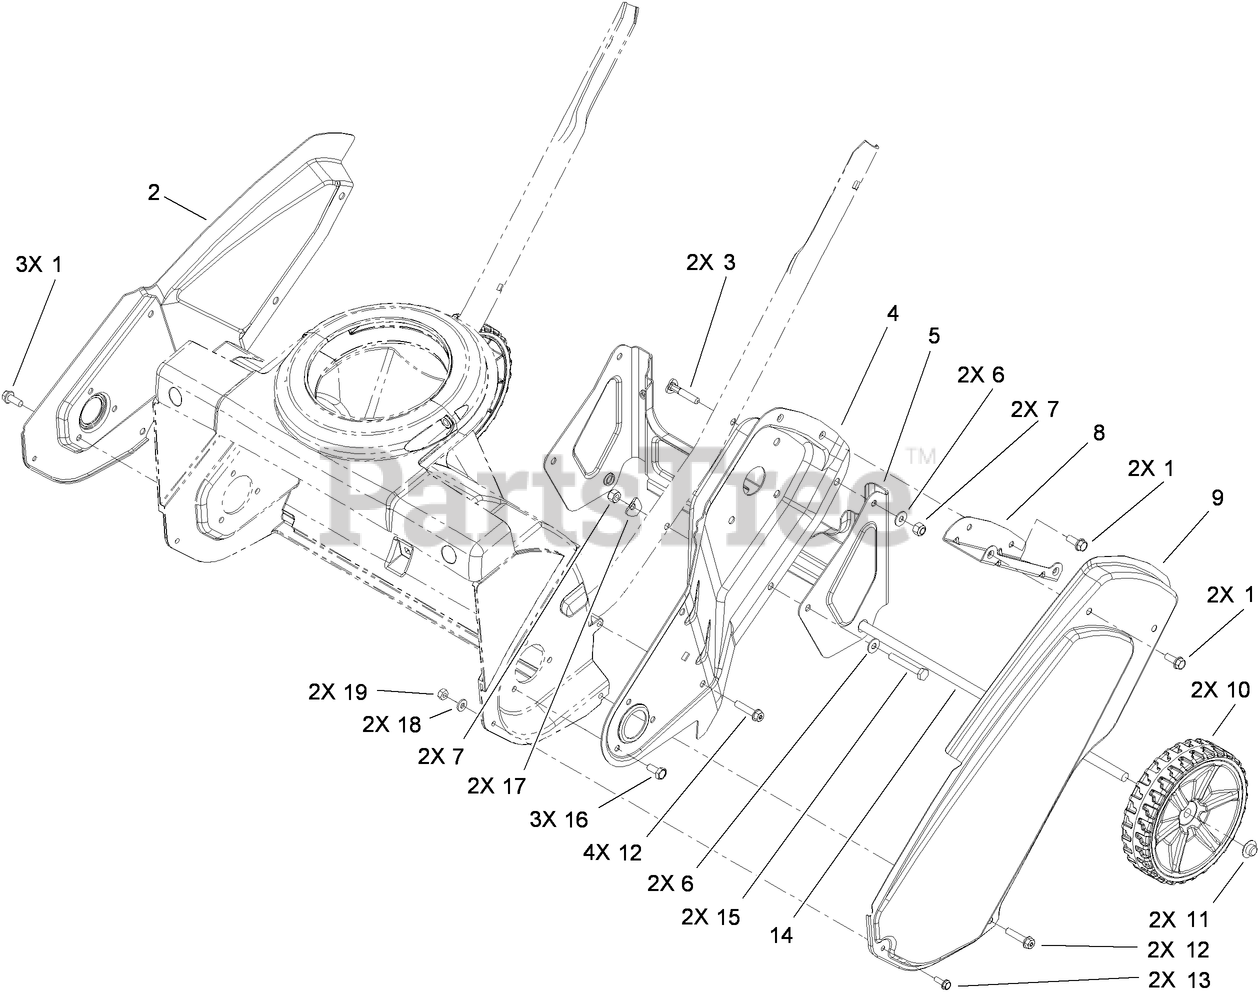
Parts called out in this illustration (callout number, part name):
1	SCREW-HWH
2	SIDEPLATE-RH
3	SCREW-HANDLE
4	SIDEPLATE-LH
5	BRACKET-WHEEL
6	WASHER-FLAT
7	NUT-LOCK, NI
8	BRACKET-COVER, BELT
9	COVER-BELT
10	WHEEL ASM
11	NUT-PUSH
12	SCREW-PLASTIC
14	AXLE
15	SCREW-HH
16	SCREW-HH, TAPTITE
17	WASHER
18	WASHER-FLAT
19	NUT-LOCK, NI
